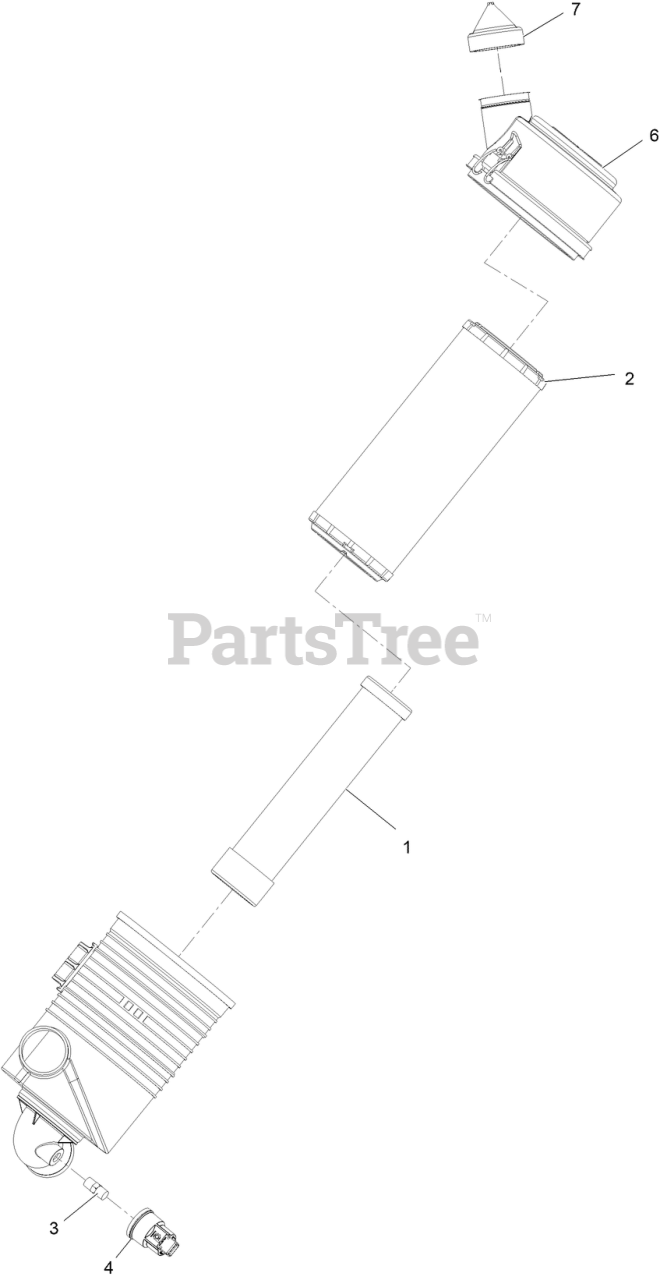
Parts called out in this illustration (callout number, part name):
1	FILTER-AIR, SAFETY
2	FILTER-AIR
3	ADAPTER-INDICATOR
4	INDICATOR-MINI
6	COVER ASM
7	VALVE-DUST-AIR CLEANER
